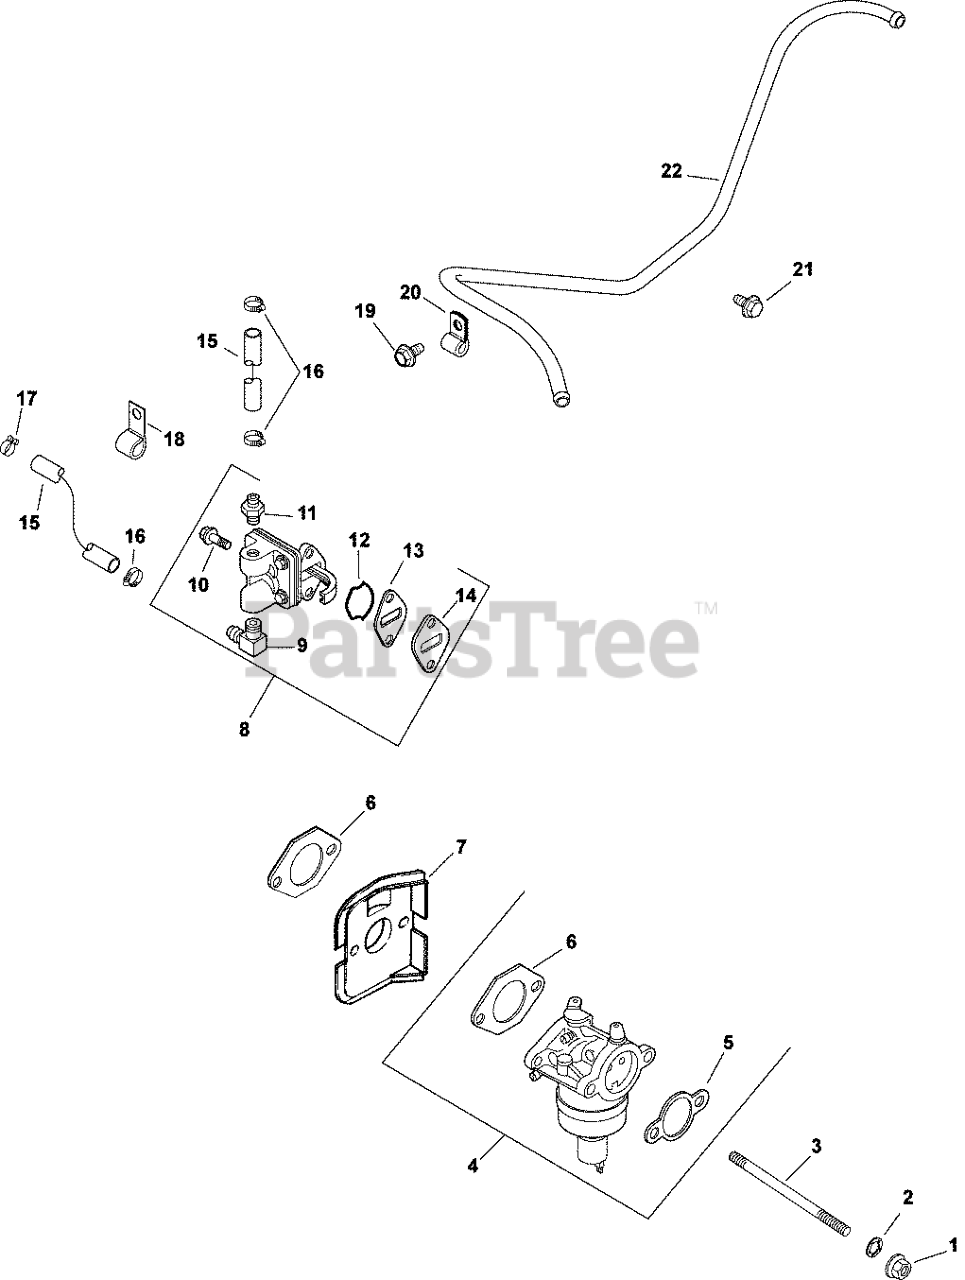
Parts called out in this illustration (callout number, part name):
1	NUT, FLG M6X1.0
2	WASHER, INT TOOTH LOCK 1/4"
3	STUD,M6X1.0X116
4	KIT, CARBURETOR - USE 12 853 178-S
5	GASKET, AIR CLEANER BASE
6	GASKET, CARBURETOR
7	DEFLECTOR, HEAT
8	KIT, FUEL PUMP
9	CONNECTOR, 90 DEG. HOSE
10	SCREW, LBD SKT M6x1.0x20-(#25086403S)
11	KIT, STRAIGHT FITTING
12	O-RING, FUEL PUMP
13	GASKET, FUEL PUMP
14	SPACER, FUEL PUMP
15	HOSE,LW PERM.FUEL 24.00"-USE 25 111 81-S
16	CLAMP, HOSE (KM)-USE 25 237 31-S
17	CLAMP, BAND SPRING HOSE-(#2523737S)
18	CLIP, CABLE
19	SCREW, THRD FRM M5X0.8X10
20	CLIP, TUBE & WIRING (KM)
21	SCREW, FLG THD FRM M5X.8X10
22	LINE, FUEL
